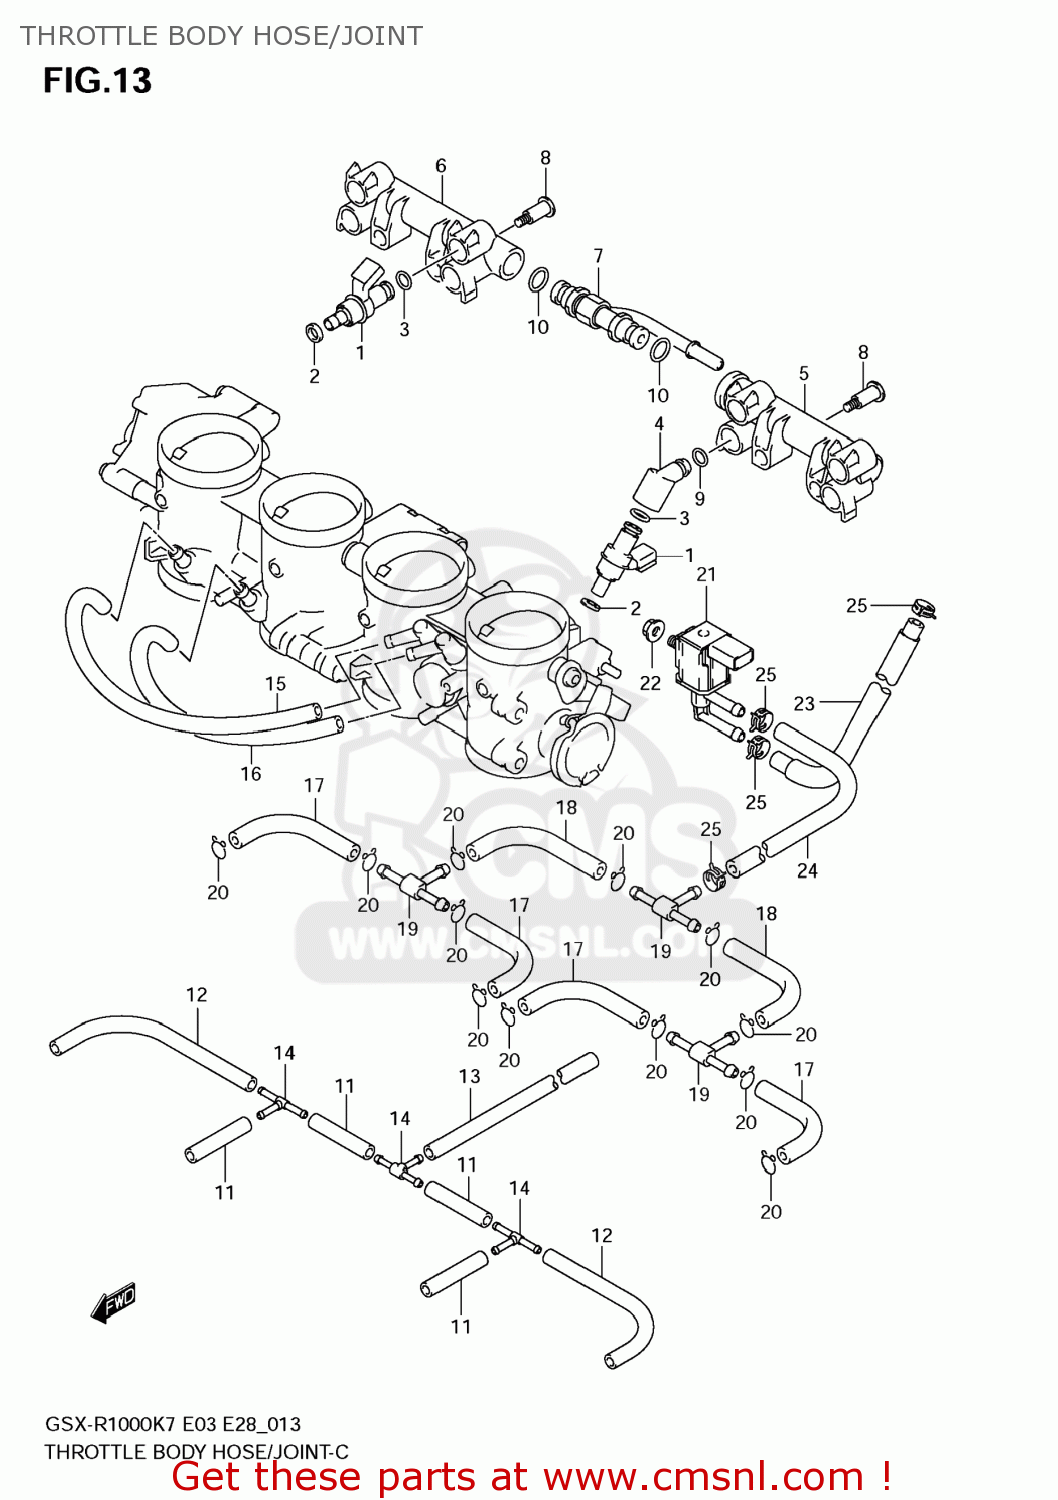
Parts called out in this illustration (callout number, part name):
1	INJECTOR ASSY
2	RING,SEAL
3	O RING
4	PIPE,FUEL
5	PIPE,FUEL
6	PIPE,FUEL
7	PIPE,FUEL
8	SCREW
9	O RING
10	O RING
11	HOSE,RUBBER(L:35)
12	HOSE,RUBBER(L:100)
13	PIPE
14	JOINT
15	TUBE
16	TUBE
17	HOSE
18	HOSE
19	JOINT
20	CLIP
21	VALVE,CANISTER PURGE
22	NUT
23	HOSE,CANISTER PURGE
24	HOSE(5.4X11.4X600)
25	CLIP
